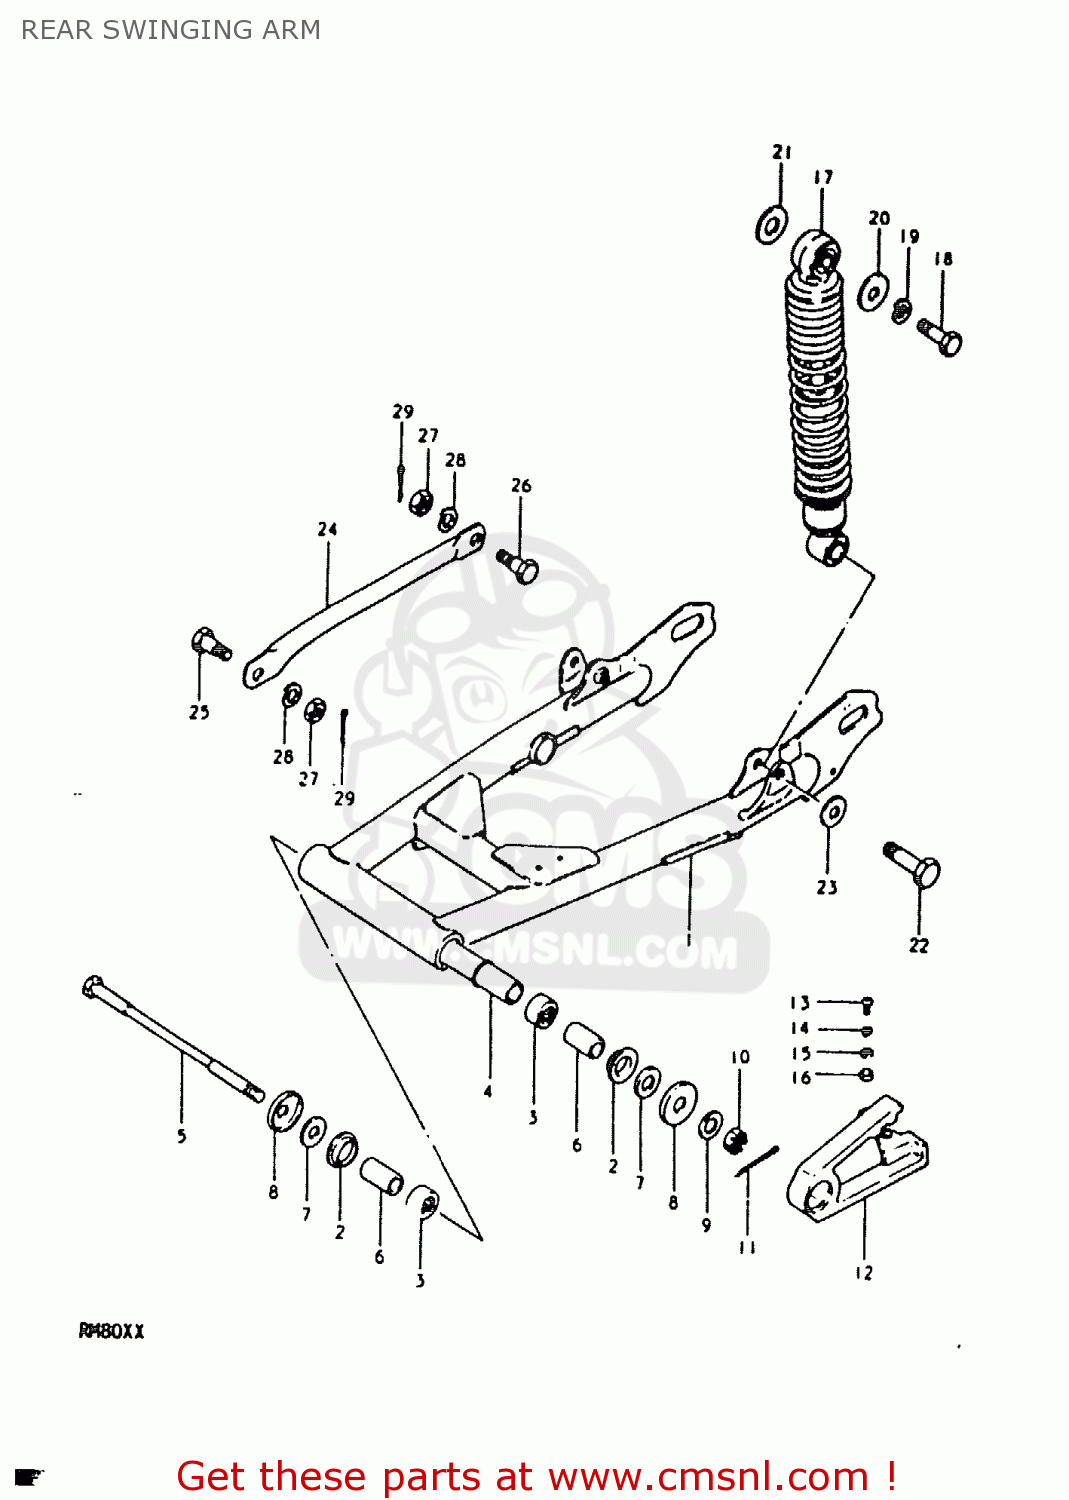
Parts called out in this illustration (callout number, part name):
1	SWING ARM ASSEMBLY,REAR
2	BUSH,RR SWINGINGARM PIVOT
3	ROLLER BEARING (17X24X2
4	SPACER,SWING ARM,CENTER
5	SHAFT,REAR SWING ARM
6	SPACER,RR SWGARM PIVOT
7	WASHER
8	COVER,REAR SWING ARM DUST
9	WASHER
10	NUT, REAR AXLE
11	COTTER PIN
12	BUFFER,CHAIN TOUCH DEFLECTOR
13	SCREW,CHAIN TOUCH DEFEND
14	LOCK WASHER
15	WASHER
16	SPACER (5.5X8X4)
17	ABSORBER ASSEMBLY,REAR SHOCK
18	BOLT
19	LOCK WASHER
20	WASHER (6.5X24X1.6)
21	WASHER
22	BOLT
23	WASHER
24	TORQUE LINK,REAR
25	BOLT(8X22)
26	BOLT(8X26.5)
27	NUT
28	LOCK WASHER
29	PIN
